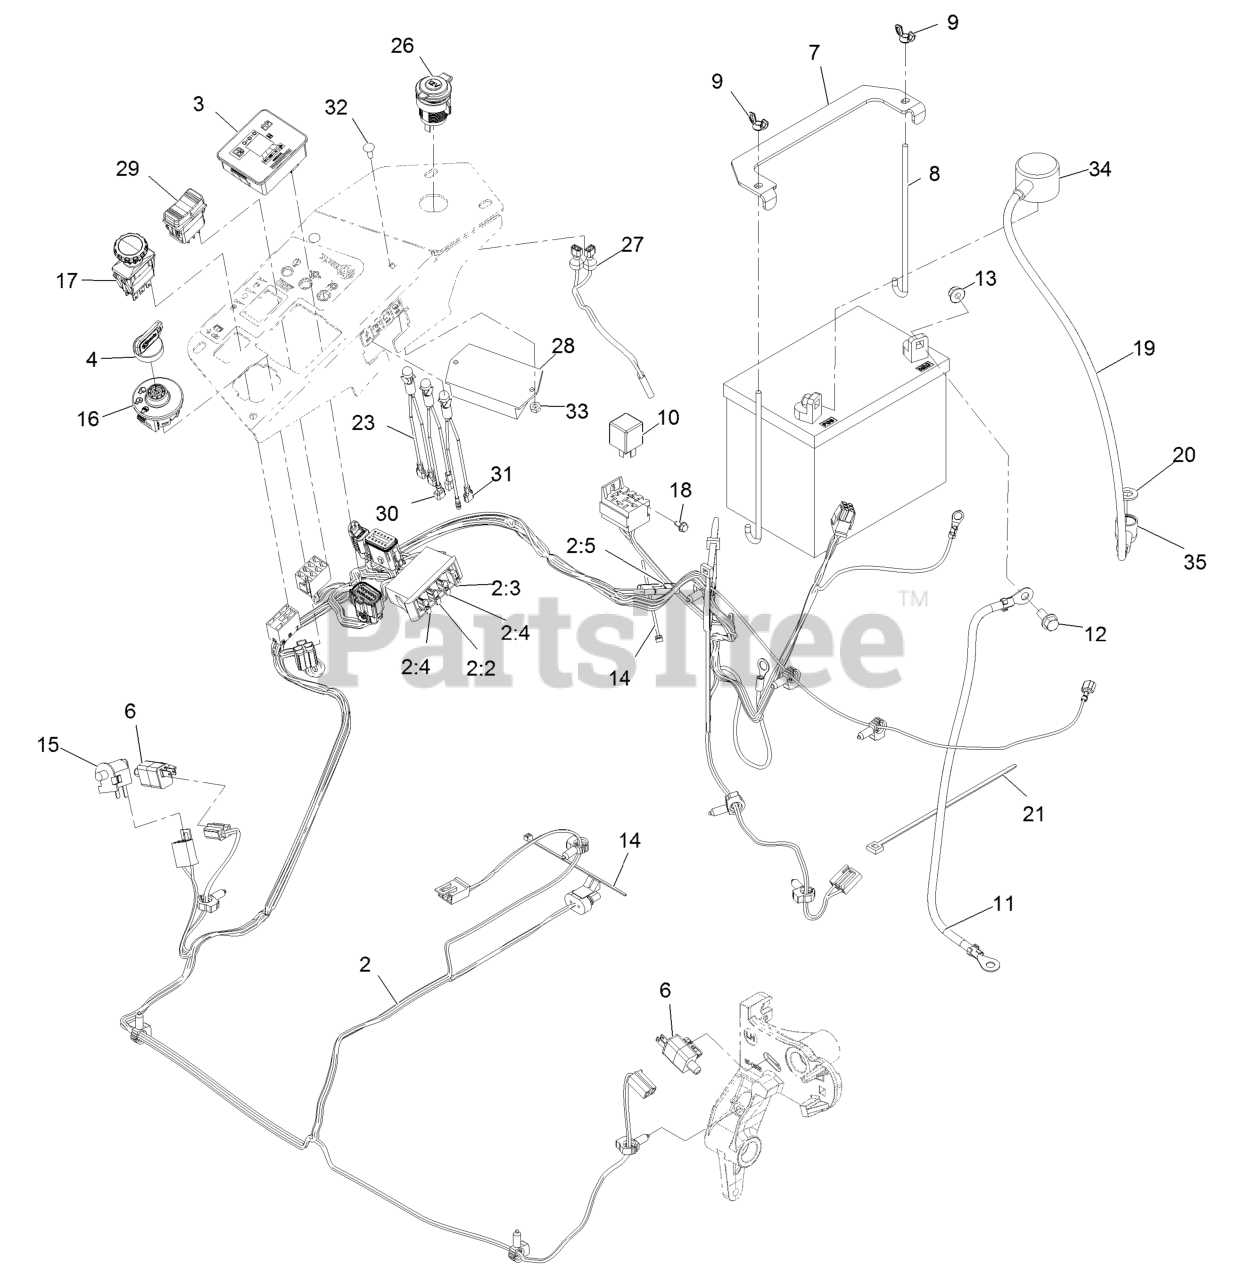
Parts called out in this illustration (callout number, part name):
2	HARNESS-WIRE
2:2	FUSE-BLADE, 10 AMP
2:3	FUSE-BLADE, 15 AMP
2:4	FUSE-BLADE, 25 AMP
2:5	CAP-PLUG
3	FUEL/HOUR METER ASM
4	KEYS-IGNITION (SPARE PAIR
4	KEY-IGNITION
7	STRAP-TIE DOWN, BATTERY
8	BOLT-HOLDDOWN
9	WINGNUT
11	CABLE-BATTERY, NEGATIVE
12	SCREW-HHF
13	NUT-HF, NI
14	TIE-CABLE
15	SWITCH-BAIL
17	SWITCH-PTO, 10 AMP
18	SCREW-HWH
19	CABLE-BATTERY, POSITIVE
20	WASHER-FLAT
21	TIE-PLASTIC
23	INDICATOR-LED, RED
26	RECEPTACLE-12V
27	HARNESS, RECEPTACLE 12V
28	CONTROLLER-RED
29	SWITCH-ROCKER
30	LIGHT-LED, RED
31	LIGHT-LED, RED
32	SCREW-CARR
33	NUT-LOCK, NI
34	INSULATOR-BATTERY
35	INSULATOR-SOLENOID
